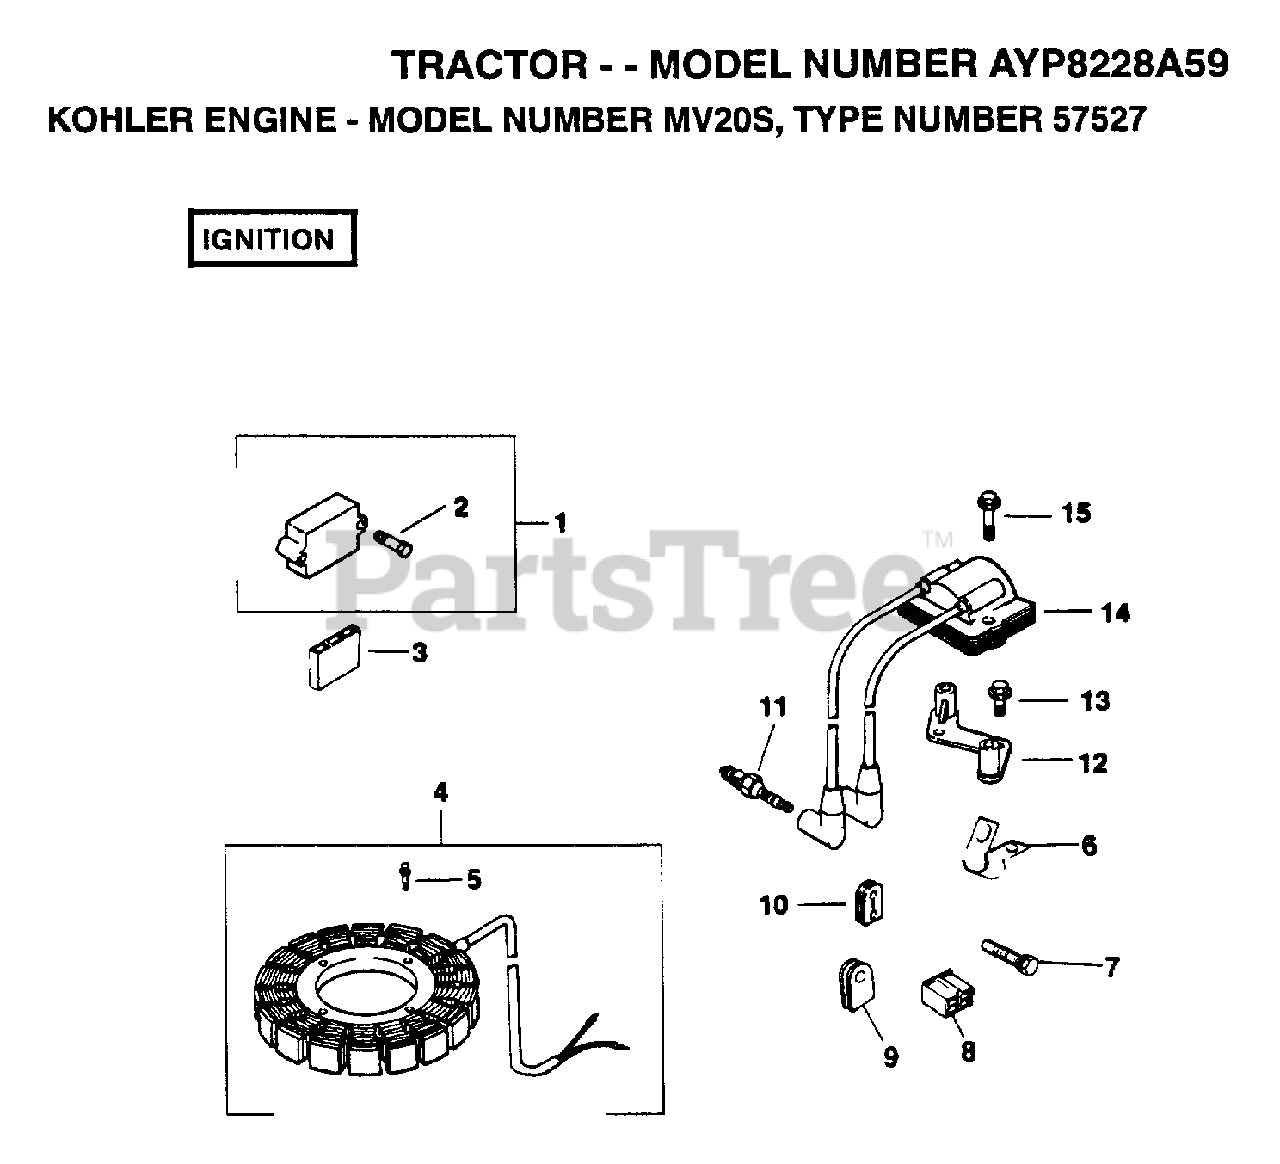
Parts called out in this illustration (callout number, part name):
2	SCREW
3	CONNECTOR
4	KIT
5	SCREW
6	CLIP
7	SCREW
8	CONNECTOR
9	GROMMET
13	SCREW, 1/4-20 X 1
